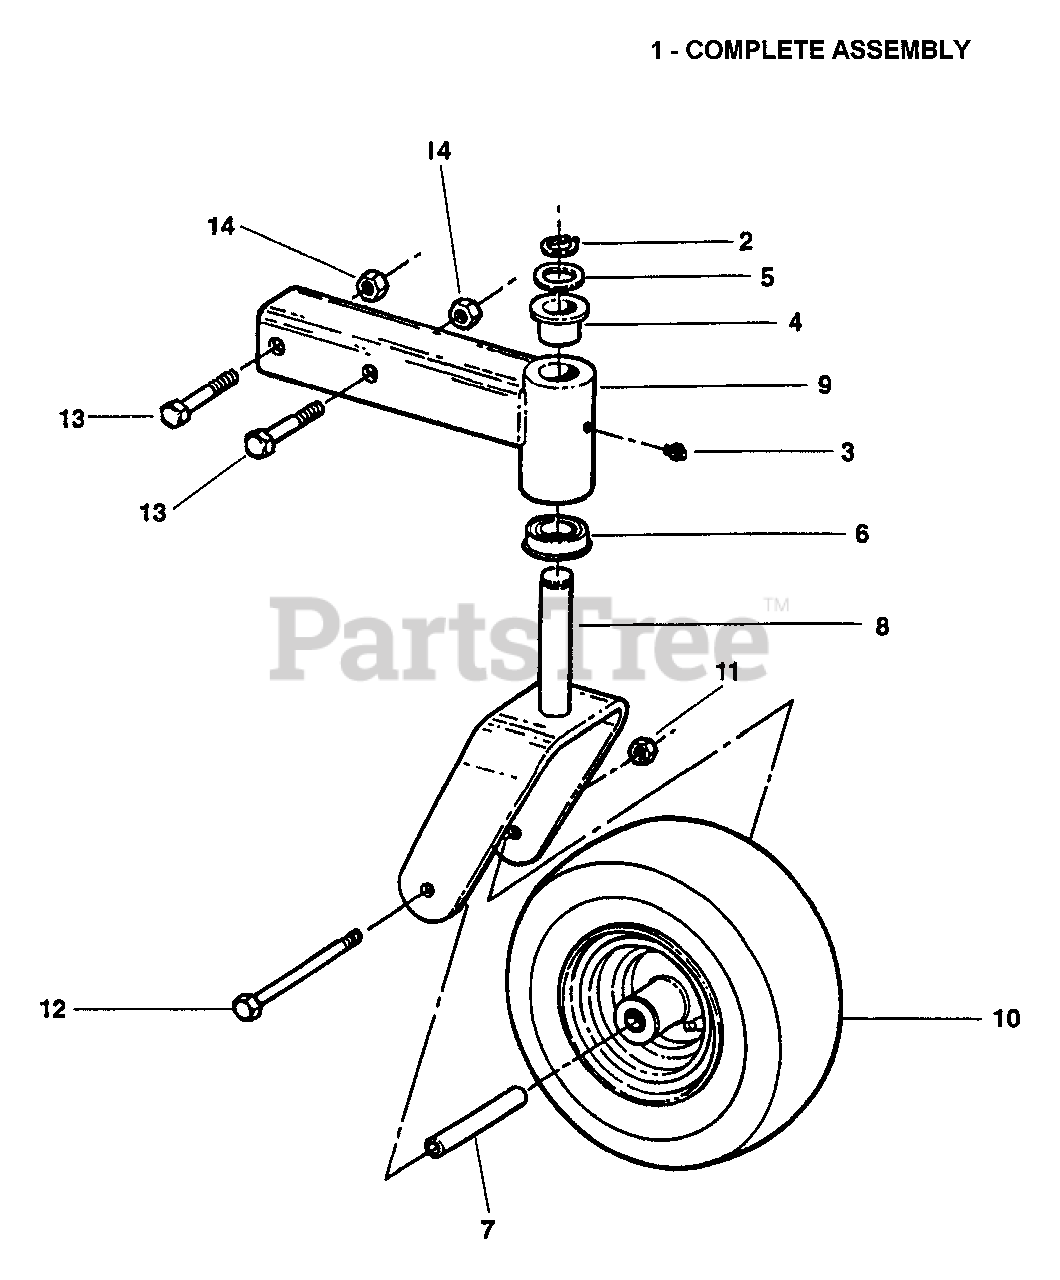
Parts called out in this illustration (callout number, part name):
1	ASSEMBLY, 11" Front Caster
2	RING, 1" External Retaining
3	LUBE FITTING, Straight (press-fit for .187 dia. Hole)
4	BUSHING, Caster
5	BUSHING, 1" Machine
6	BEARING, Flanged Ball
7	TUBE, 5/8" O.D.x 18 Gage Wall x 3.545 Long
8	YOKE, Caster (Weldment)
9	ARM, Telescoping Caster (Weldment)
10	ASSEMBLY, Wheel
11	NUT, 7/16-14 Hex Head Cap
12	SCREW, 7/16-14 x 6" Hex Head Cap
13	BOLT, 1/2-13 X 3" GD5 CZ
14	NUT, 1/2-13 HEX NYLON LOCK
